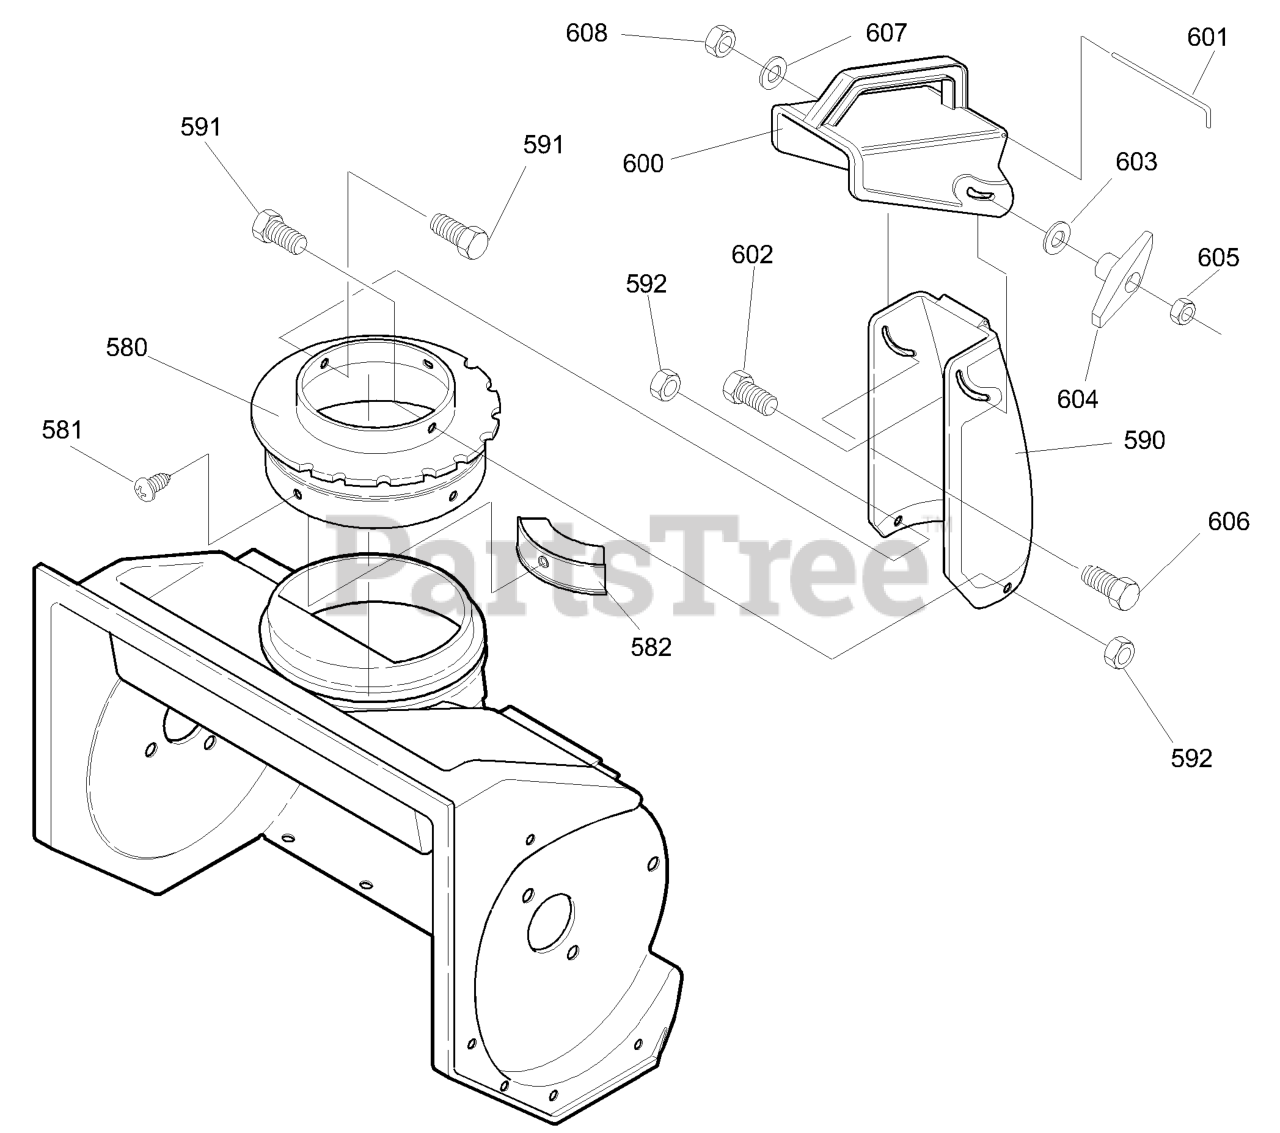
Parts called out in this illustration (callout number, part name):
580	RING, CHUTE
582	GUIDE, CHUTE
590	CHUTE, LOWER
591	SCREW 1/4-20X.50
592	NUT, 1/4-2
600	CHUTE, UPPER
601	WIRE, HINGE
602	BOLT, 5/16-18X1.25
603	WASHER, FLAT
604	KNOB, T
605	NUT, 5/16-18
606	SCREW, 5/16-18 x 0.75
607	WASHER, FLAT
608	NUT, 5/16-18
